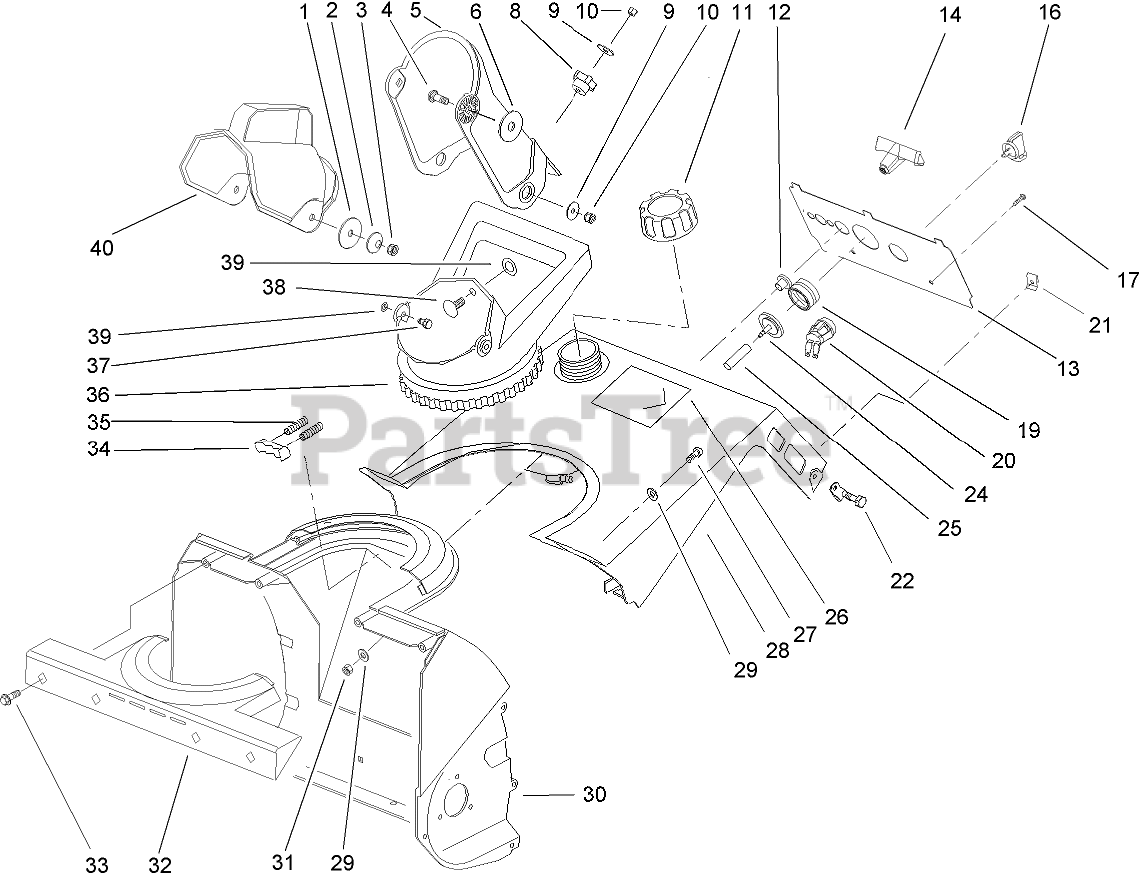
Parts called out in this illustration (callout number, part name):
1	WASHER-FLAT
2	WASHER-BELLEVILLE
3	NUT-LOCK, NI
4	BOLT-CARR
5	CHUTE
6	WASHER-RUBBER
8	KNOB-CHUTE
9	WASHER-FLAT
10	NUT-LOCK, NI
11	GAS CAP ASM
12	GUIDE-ROPE, STARTER
13	CONTROL PANEL-SILKSCREENED
14	HANDLE-STARTER
16	KEY-IGNITION
17	SCREW-SHWH, THREAD FORMING
19	BULB-PRIMER
20	SWITCH
22	SCREW-THREAD FORMING
24	BODY-PRIMER
25	HOSE-PRIMER
26	DECAL-ELECTRIC START
27	SCREW-PPH
28	SHROUD-TANK, GAS UPPER
29	WASHER-FLAT
30	HOUSING
31	NUT-LOCK, NI
32	RETAINER-CHUTE
33	SCREW-PLASTIC
34	DETENT-CHUTE
35	SPRING-COMPRESSION
36	HANDLE-CHUTE
37	SCREW-HH
38	SCREW-CARR
39	PUSHNUT-RETAINER, BOLT
40	DEFLECTOR-CHUTE
